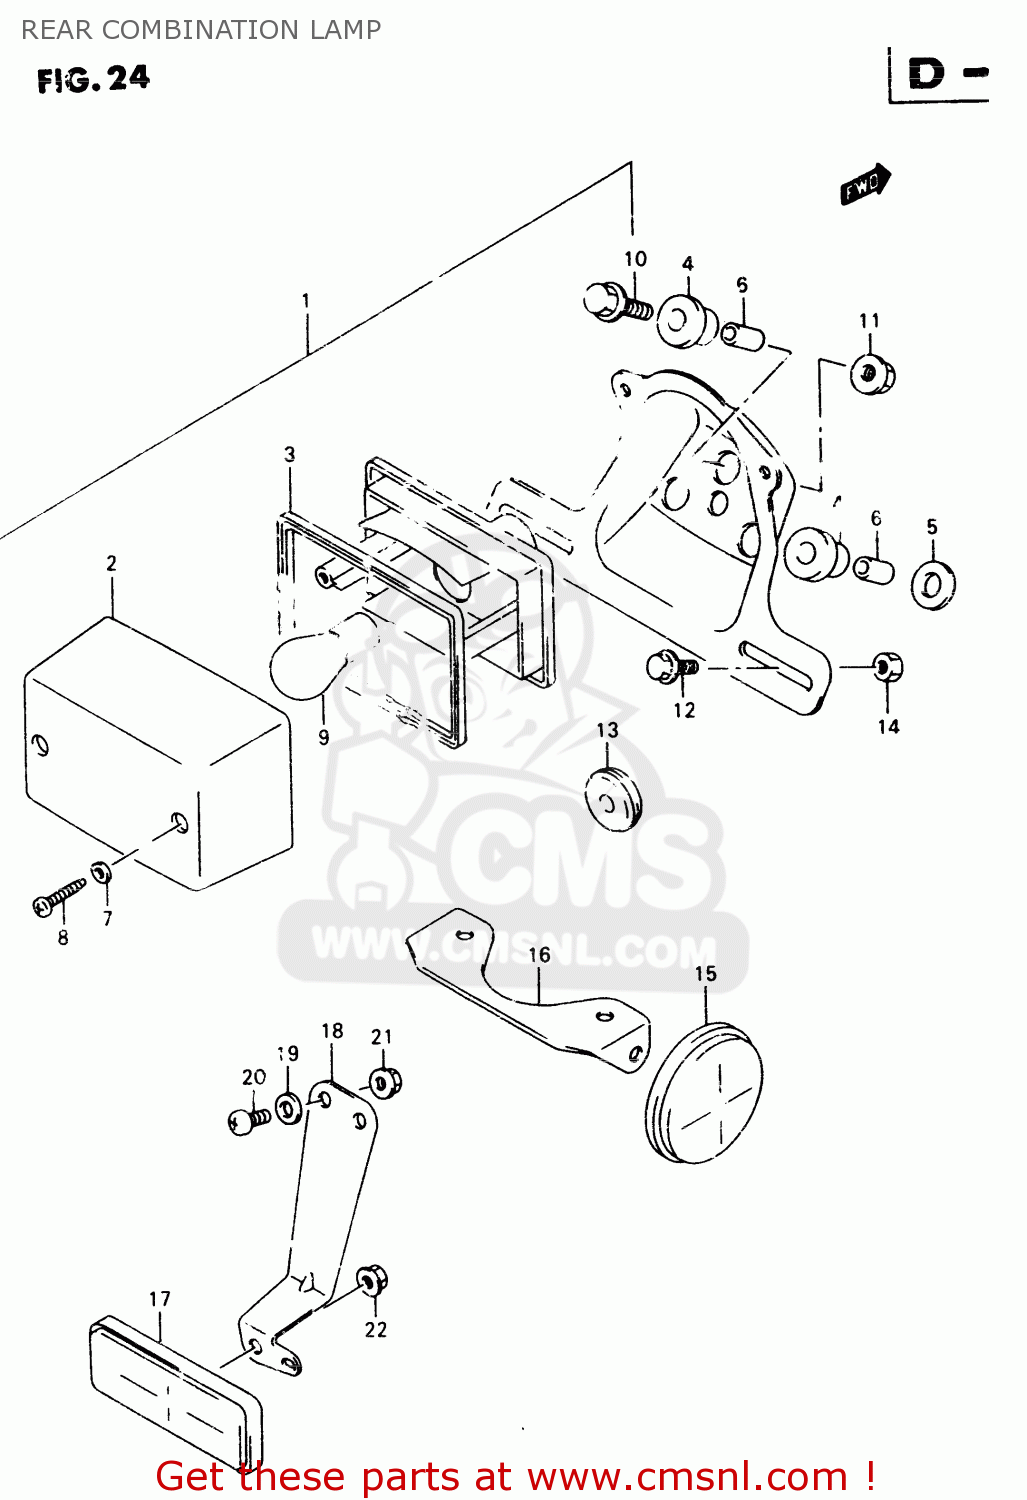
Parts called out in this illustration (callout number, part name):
1	LAMP ASSY,RR COMBINATION
2	LENS
3	GASKET,RR COMBI LAMP LENS (NAS)
4	CUSHION
5	CUSHION
6	SPACER
7	GASKET (NAS)
8	SCREW
9	BULB(12V21/5W)
10	BOLT(6X20)
11	NUT
12	BOLT(6X20)
13	GROMMET
14	NUT
15	REFLECTOR,REFLEX FR
16	BRACKET, REAR
17	REFLECTOR ASSY,RR
18	BRACKET,RR REFLECTOR
19	WASHER(5.5X16X1.2)
20	SCREW
21	NUT
22	NUT
